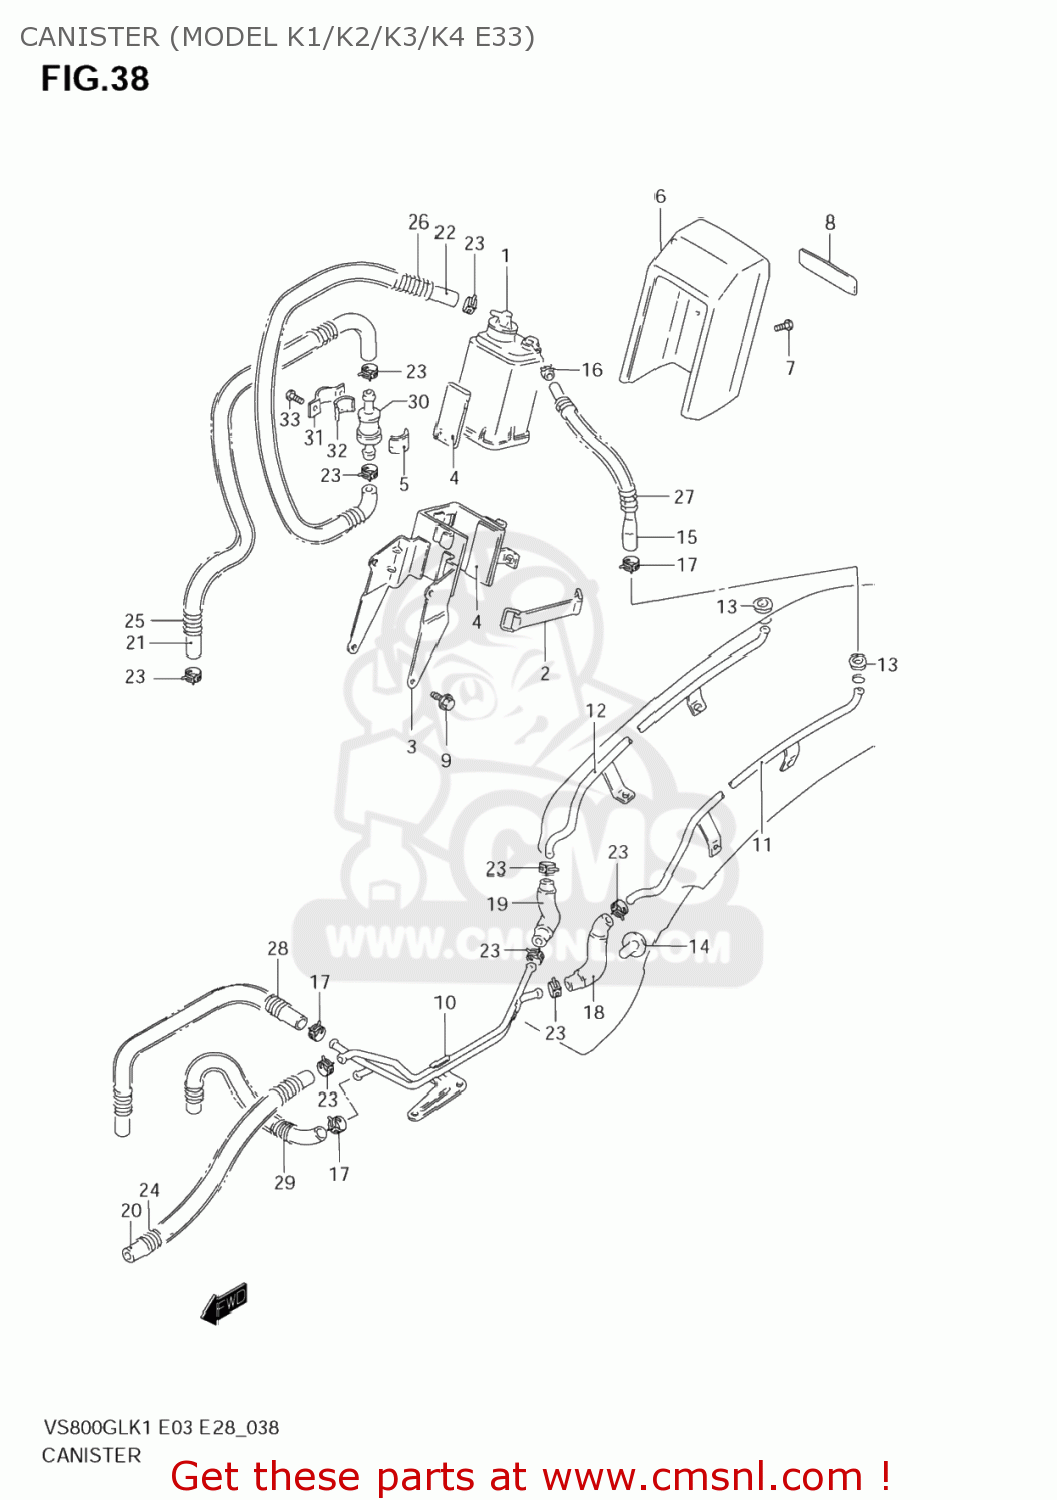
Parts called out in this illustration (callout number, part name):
1	CANISTER ASSY,CHARCOAL
2	BAND
3	PLATE,CANISTER FITING
4	CUSHION
5	CUSHION
6	COVER,CANISTER
7	SCREW
8	EMBLEM,TOOL HOLDER RR
9	BOLT
10	PIPE,CSTR JOINT FR
11	(CA) PIPE,CANISTER JOINT REAR
12	(CA) PIPE,CANISTER JOINT REAR
13	GROMMET
14	GROMMET
15	HOSE,PURGE NO.1
16	CLIP
17	CLIP
18	(CA) HOSE NO.6
19	(CA) HOSE NO.2
20	HOSE(5.4X11.4X600)
21	HOSE
22	HOSE
23	CLIP
24	SPRING
25	(CA) SPRING
26	SPRING
27	SPRING
28	SPRING
29	SPRING
30	VALVE,FUEL TANK BREATHER
31	PLATE,FUEL TANK BREATHER NO.2
32	CUSHION
33	SCREW
